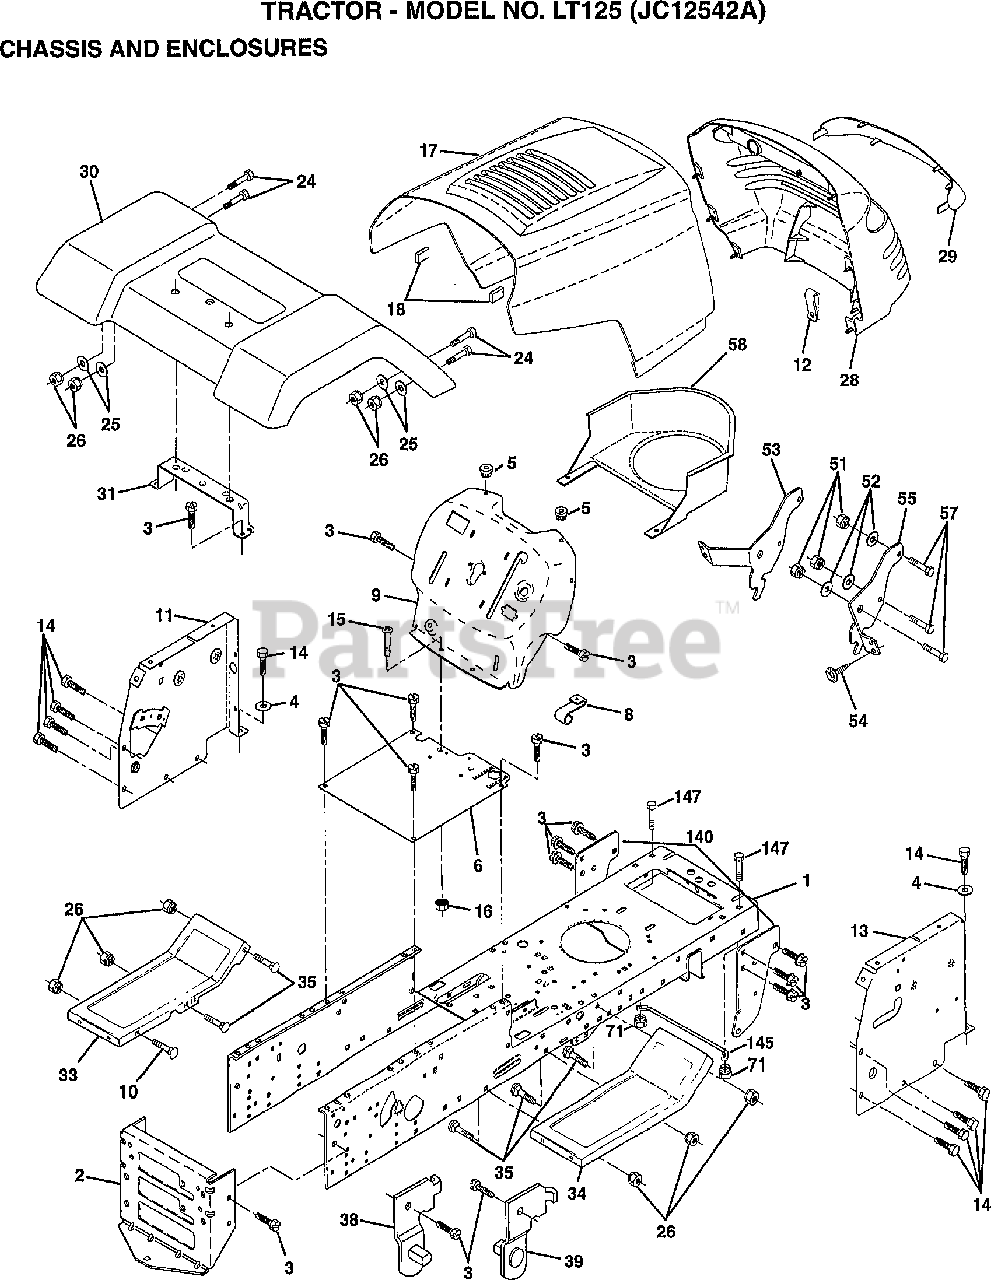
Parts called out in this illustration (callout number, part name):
3	SCREW THDROL 3/8-16X3/4 TY-TT
4	WASHER 13/32X3/4X16 GA
10	BOLT CARRIAGE 3/8-16X1
14	SCREW THDROL 3/8-16X1/2 TY-TT
15	SCREW MACHINE TRHD 5/16-18 X 3/4
16	NUT, KEPS 5/16-18
18	"BUMPER,HOOD T"
24	BOLT FIN HEX 3/8-16 X 1
25	WASHER
26	LOCKNUT
35	BOLT RDHD SHT SQNK 3/8-16 X 3/4
51	NUT LOCK HEX W/INS 1/4-20
52	WASHER 9/32 X 7/8 X 16 GA
54	SCREW LOCK SPIDER #8 X 7/8
57	BOLT HEX 1/4-20 X 3/4
71	NUT CROWNLOCK 1/4-20
147	BOLT HEX HD 1/4-20 X 3/4
